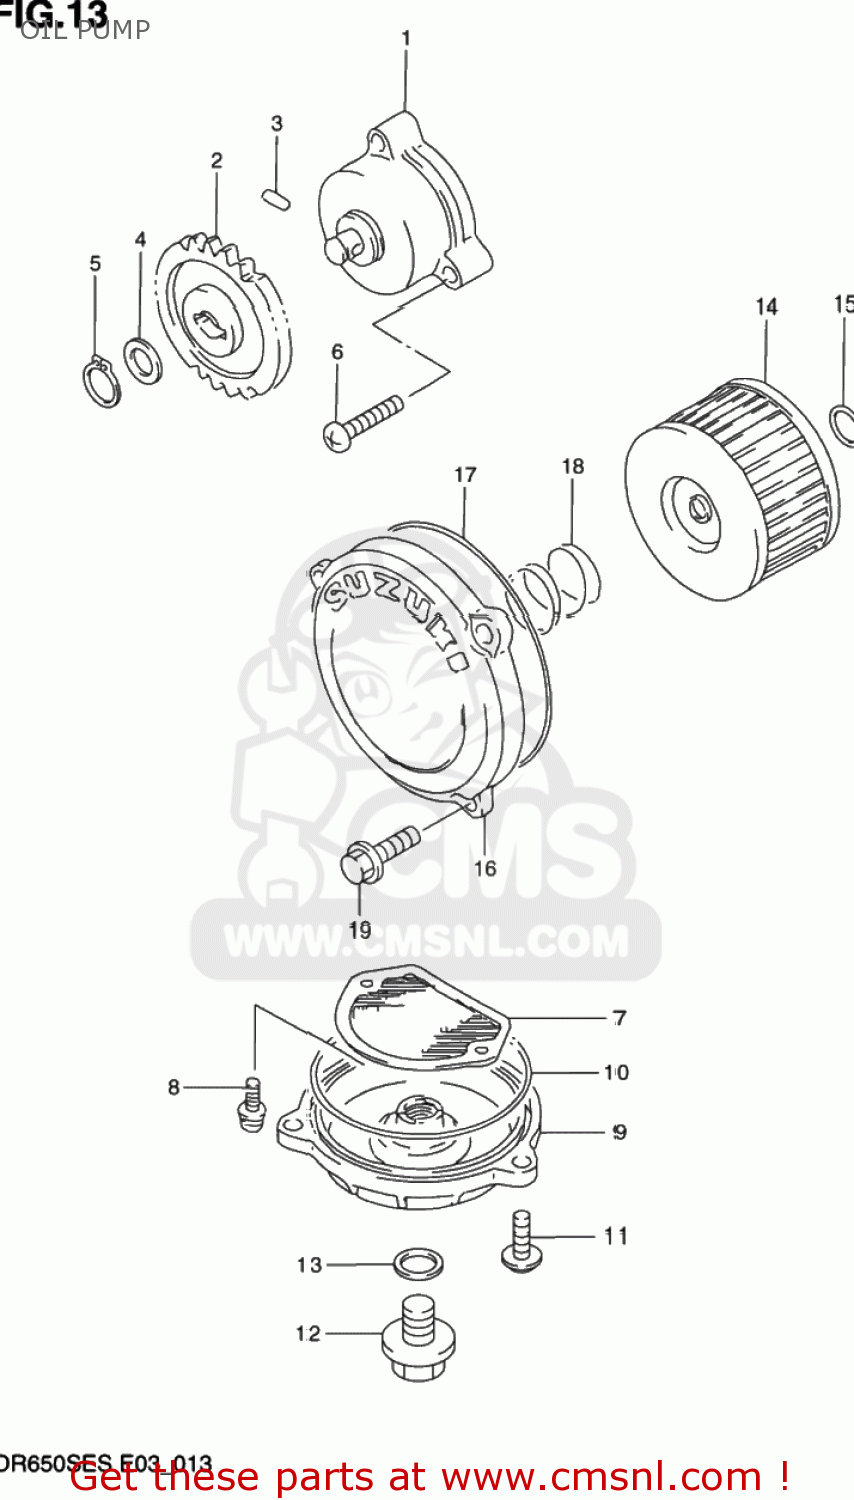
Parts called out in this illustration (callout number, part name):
1	PUMP ASSY,ENGINE OIL
2	GEAR,OIL PUMP DRIVEN
3	PIN(4X15.8)
4	SHIM
5	CIRCLIP,10MM
6	SCREW
7	STRAINER,ENGINE OIL
8	SCREW
9	CAP,OIL STRAINER
10	O RING(D:2.4,ID:85)
11	BOLT
12	PLUG
13	GASKET(14X19.2X2) (NAS)
14	FILTER,ENGINE OIL
15	O RING(D:2.4,ID:15.8)
16	CAP,OIL FILTER
17	O RING(D:2.4,ID:73)
18	SPRING
19	BOLT
